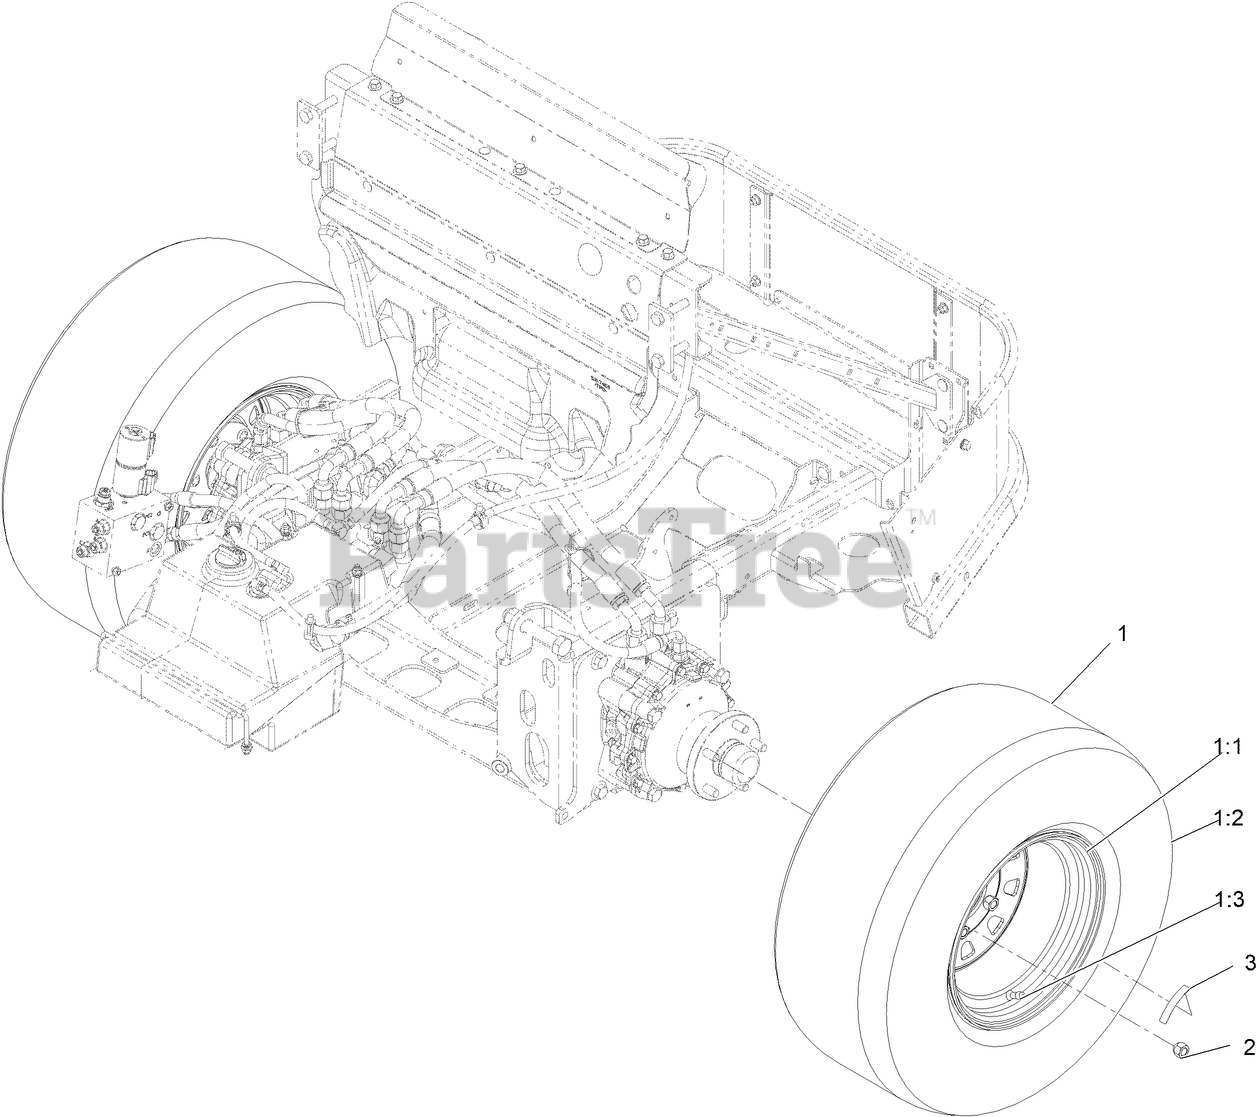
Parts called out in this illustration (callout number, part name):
1	ASM-TIRE 26X12-12, 1.0 OFFSET
1:1	RIM ASM, 1.0 OFFSET
1:3	Stem-Valve
2	NUT-LUG
3	DECAL-TORQUE, WHEEL NUT
